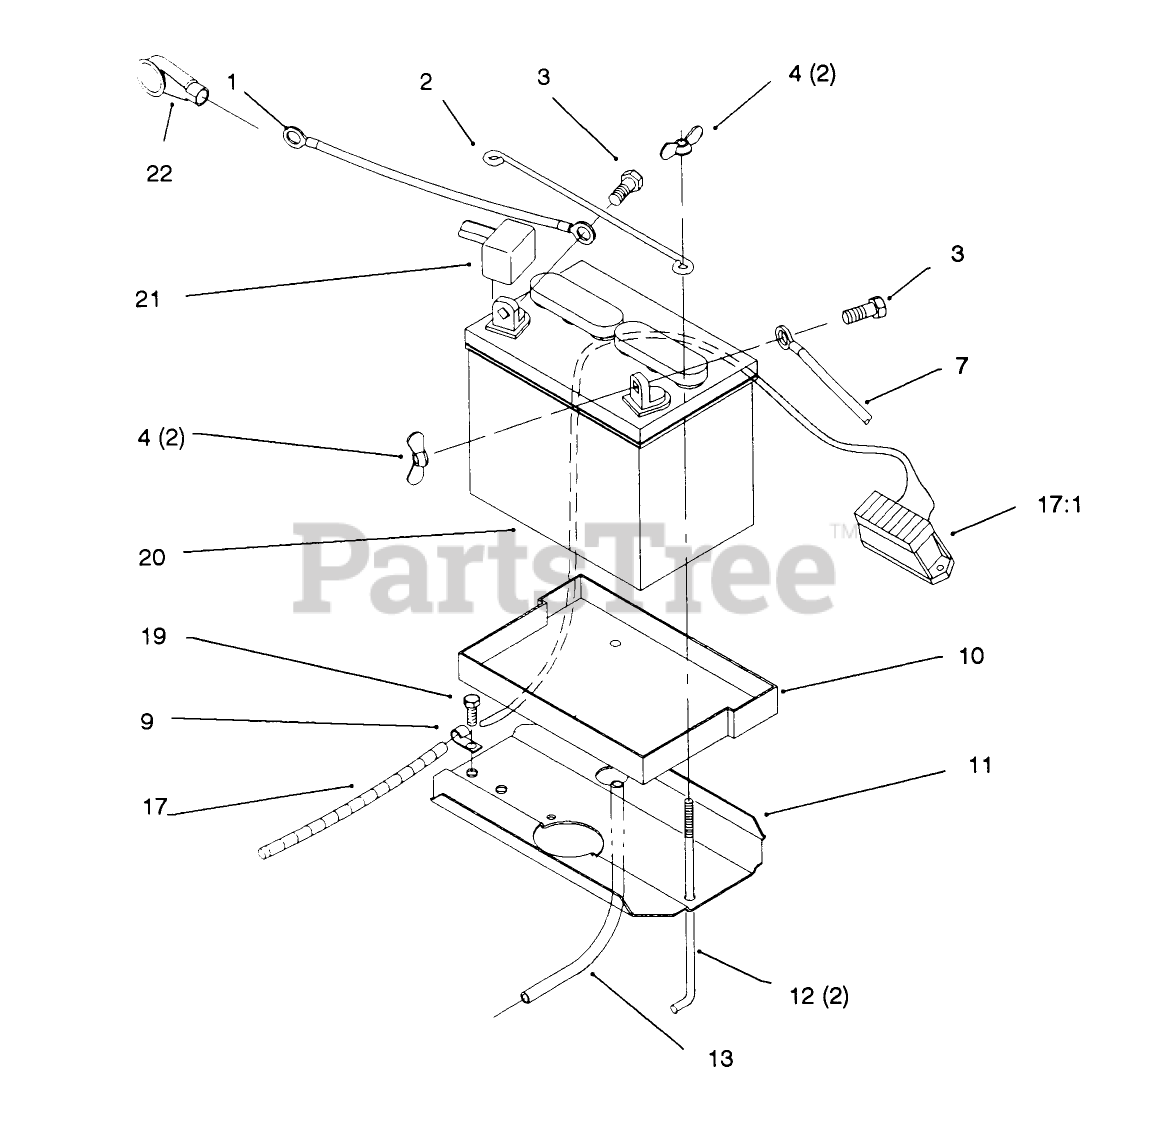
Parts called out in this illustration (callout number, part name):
1	WIRE-21 INCH
1	WIRE -10" RED
2	ROD-BATTERY HOLD DWN
3	SCREW-HH
4	NUT-WING
7	WIRE -BLACK
7	CABLE
9	CLIP
10	TRAY-BATTERY
11	Plate-Battery
13	TUBE-21" BATTERY DRAIN
17	WIRE HARNESS
19	SCREW-HWHTF
22	BOOT-INSULATOR, TERMINAL
